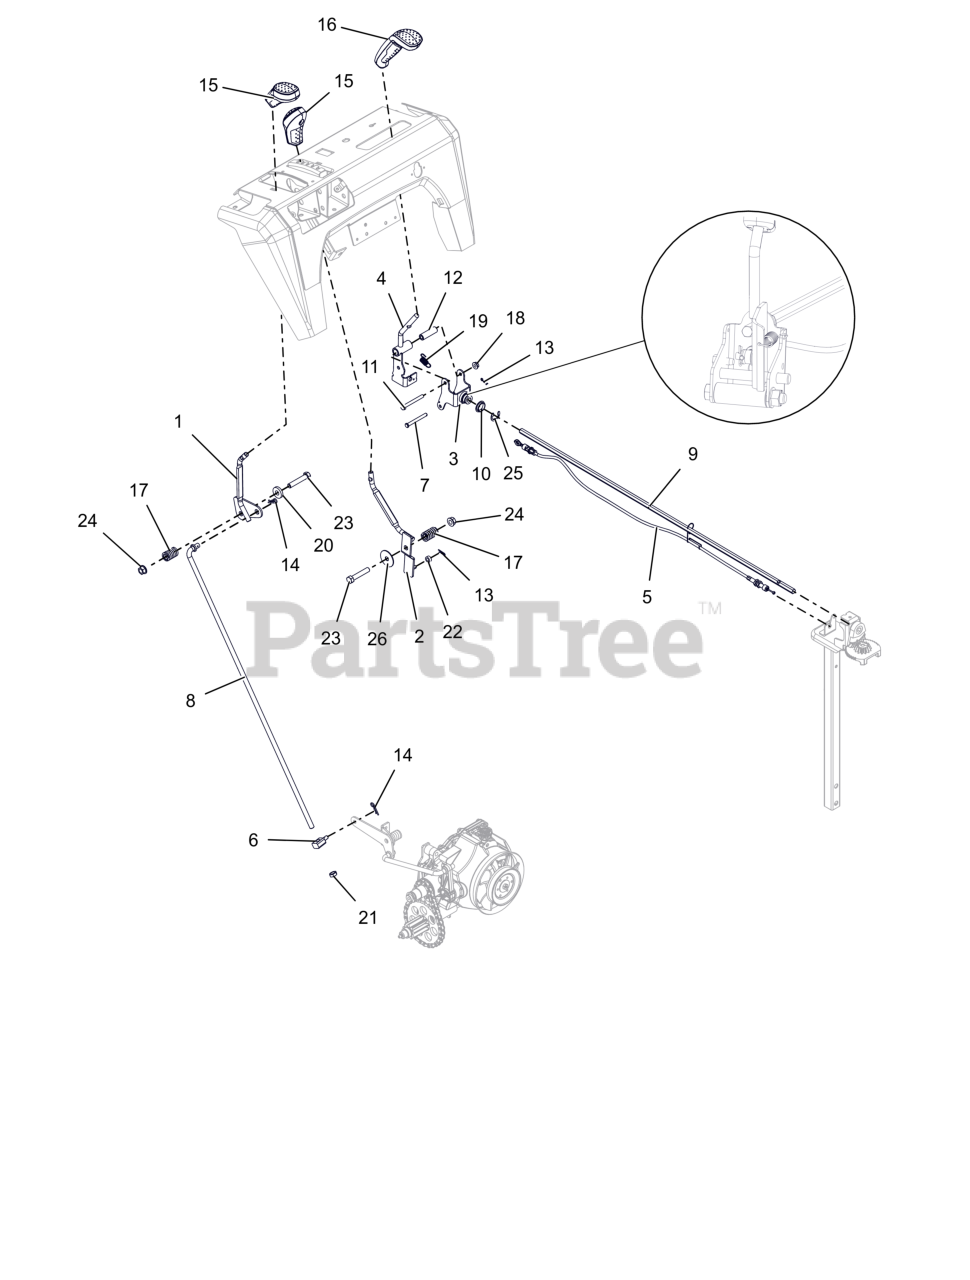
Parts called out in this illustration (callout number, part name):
1	WELDMENT,LG DASH SPEED CONTROL
2	WELDMENT,LG DASH DEFL CONTROL
3	WELDMENT, CONTROL BRACKET
4	WELDMENT, CONTROL LEVER
5	CABLE, CHUTE LOCK, PRO
6	PIVOT,SHIFT ROD .375-16(TRUNN)
7	PIN, CLEVIS - .25 X 2.25 ZCC
8	ROD, SHIFT - PRO
9	ROD, HEX - CHUTE ROTATION
10	BUSHING, POLYLINER-.75 SNAPIN
11	BLT,HEX .25-20X2.25 G5 ZCC
12	BSHG, SLV .265X.505X1.665
13	PIN, HAIR #178 .06X.77 ZCC
14	PIN, HAIR #213 .08X1.19 ZCC
15	KNOB, CONTROL, DASH
16	HANDLE, QUICK TURN, ASM
17	SG-COMP .125X.781X1.250
18	NUT-LK-CTR-FLG .25-20 ZC120
19	SPRING-EXT .047X.438X1.45
20	WSHR, FLT .406X1.00X.188 ZCC
21	NUT-JAM .375-16 G2 ZCC
22	BSHG-SLV .265X.500X.219
23	BLT,HEX .38-16X2.00 G5 ZCC
24	NUT-LK-TOP-FLG .38-16 ZC120
25	E-RING .750X.050
26	WSHR,FLT .380X1.50X.062 ZCC
